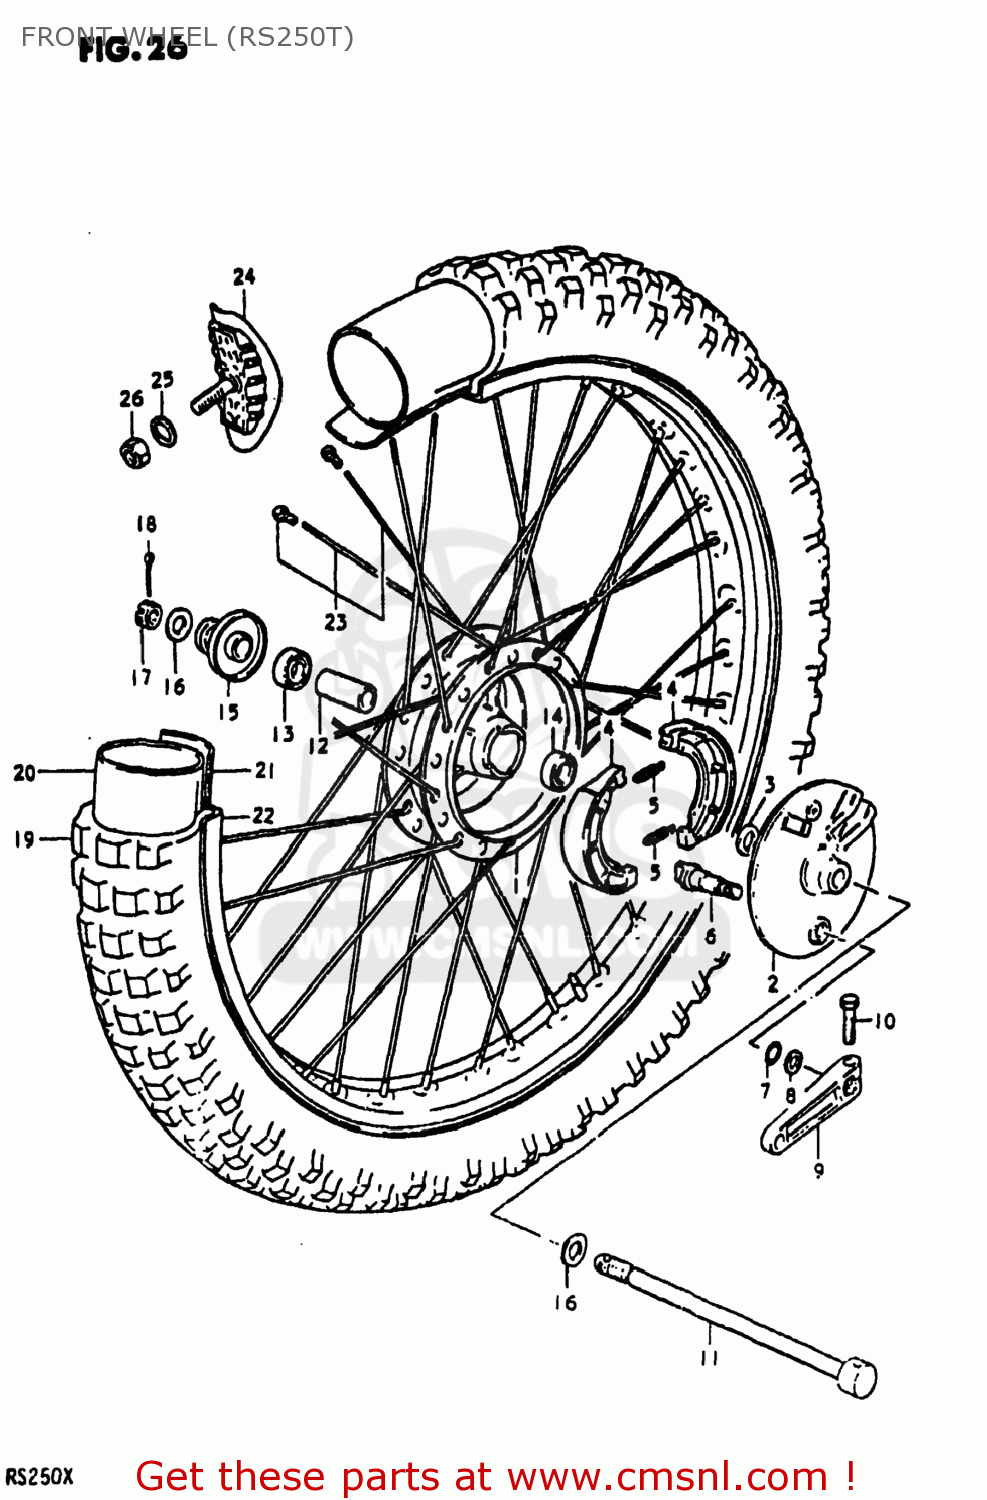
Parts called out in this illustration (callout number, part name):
1	HUB,FRONT
2	PANEL,FRONT HUB
3	BOSS
4	SHOE,BRAKE
5	SPRING(L:34)
6	CAM,FRONT BRAKE
7	O RING(D:2.5,ID:11.4)
8	WASHER(12.5X20X1)
9	LEVER,FRONT BRAKE CAM
10	BOLT
11	AXLE,FRONT
12	SPACER (12.6X19X52)
13	BEARING, RH
14	BEARING
15	SPACER,FRONT AXLE,RIGHT
16	WASHER
17	NUT, REAR AXLE
18	COTTER PIN
19	TIRE,FRONT
20	TUBE
21	PROTECTOR,WHEEL,INNER
22	RIM,FRONT WHEEL
23	SPOKE SET,FRONT
24	STOPPER,BEAD
25	WASHER
26	NUT
